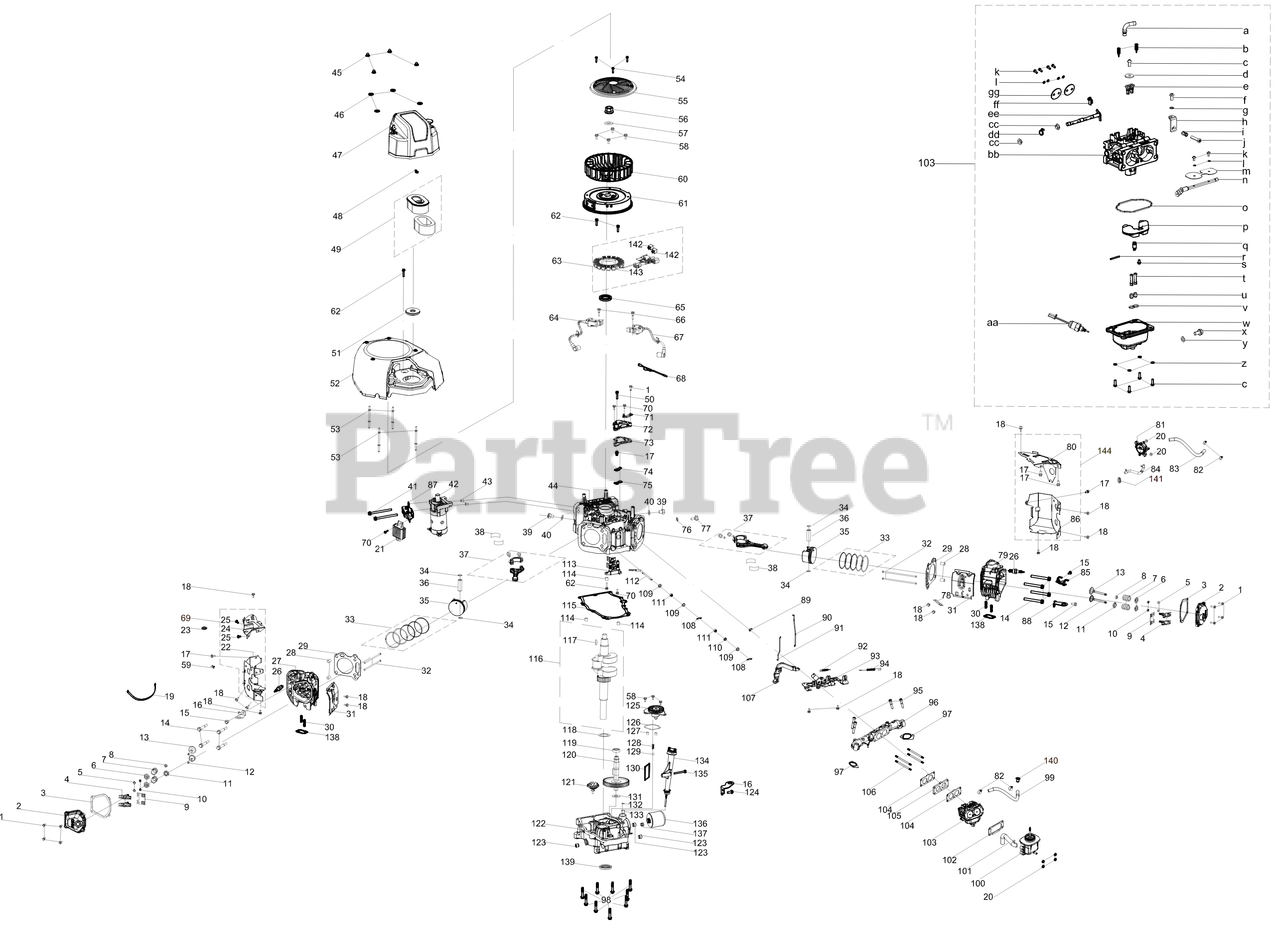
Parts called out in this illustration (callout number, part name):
1	BOLT M6 x 22
2	VALVE COVER
3	VALVE COVER GASKET
4	ROCKER ARM ASSEMBLY
5	EXHAUST VALVE ADJUSTER
6	VALVE SPRING SEAT
7	VALVE SPRING
8	INTAKE VALVE SEAL
9	PUSH ROD GUIDE
10	VALVE CAP
11	VALVE SPRING RETAINER
12	EXHAUST VALVE
13	INTAKE VALVE
14	HEX HEAD BOLT - M10X1.25X87
15	HEX HEAD BOLT M8X16
16	LIFT HOOK BRACKET - LH
17	BOLT M6-1 x 10 GR8.8
18	BOLT M6-1 x 12 GR8.8
19	CABLE TIE - 3 x 150
20	HEX NUT
21	REGULATOR
22	CYLINDER HEAD BAFFLE
23	HEAT SHIELD GROMMET
24	FLYWHEEL SHROUD - LH
25	HEX HEAD SCREW M6X10
26	SPARK PLUG
27	CYLINDER HEAD - LH
28	DOWEL PIN
29	CYLINDER HEAD GASKET
30	STUD M8 x 36
31	SHROUD
32	PUSH ROD
33	PISTON RIN SET
34	PISTON PIN SNAP RING
35	PISTON ASSEMBLY
36	PISTON PIN
37	CONNECTING ROD
38	CONNETING ROS BEARING
39	HEX HEAD BOLT M14-1.5X1.5
40	FLAT WASHER 14X1.5X22
41	HEX HEAD BOLT M8X110
42	ELECTRIC STARTER
43	DOWEL PIN
44	CRANKCASE
45	ACORN NUT
46	WASHER
47	AIR FILTER COVER ASSEMBLY
48	WING NUT
49	AIR FILTER ELEMENT
49	Genuine Factory Parts AIR FILTER
50	BOLT-M6-1 x 28 GR8.8
52	BLOWER HOUSING
53	STUD - M6-1.0X69.8X117
54	BOLT 5.5 x 25
55	DEBRIS SHIELD
56	NUT M20 x 1.5
57	WASHER 20.5 x 5 x 40
58	BOLT M6-1 x 18 GR8.8
59	PLASTIC SUPPORT CLAMP
60	COOLING FAN
61	FLYWHEEL
62	BOLT M6-1 x 25 GR8.8
63	CHARGING COIL
64	IGNITION MODULE (LH)
65	OIL SEAL 38 x 58 x 8
66	BOLT-M6-1 x 30 GR8.8
67	IGNITION MODULE (RH)
68	WIRE HARNESS
69	SHROUD ASSEMBLY (LH)
70	BOLT M6 x 16
71	FLYWHEEL GUARD BRACKET
72	BEATHER COVER
73	BREATHER COVER GASKET
74	BREATHER REED BRACKET
75	BREATHER REED ASSEMBLY
76	WASHER 20.5X1.5X18
77	HEX HEAD BOLT M10X1X10
79	CYLINDER HEAD - RH
80	SHROUD (RH)
81	FUEL PUMP
82	HOSE CLAMP
83	FUEL HOSE
84	FUEL LINE
85	MOUNTING BRACKET
86	CYLINDER HEAD BAFFLE
87	STARTER RELAY SUPPORT
88	REAR LIFT BRACKET
89	CHOKE LINKAGE LOCK CLAMP
90	THROTTLE LINKAGE
91	CHOKE LEVER
92	GOVERNOR SPRING
93	GOVERNOR GEAR BRACKET ASSEMBLY
94	GOVERNOR SPRING
95	SCREW - M8X50
96	INTAKE MANIFOLD
97	INTAKE MANIFOLD GASKET 9Q78
98	HEX HEAD FLANGE BOLT M8X48
99	FUEL LINE 6.3 x 12.5 x 470
100	INTAKE MANIFOLD
101	BREATHER HOSE
102	AIR FILTER HOUSING GASKET
103	CARBURETOR
104	CARBURETOR GASKET
105	INSULATOR
106	STUD M6-1 x 105
107	GOVERNOR LEVER
108	GOVERNOR SHAFT CLIP
109	FLAT WASHER 8.5X15.8X2
110	GOVERNOR SEAL
111	NEEDLE BEARING 8X12X10
112	GOVERNOR ARM ROD
113	ROACKER ARM
114	PIN 8X12
115	CRANKCASE GASKET
116	CRANKSHAFT ASSEMBLY
117	FLYWHEEL KEY
118	WASHER - 38.5X1.0X54
119	CAMSHAFT BEARING
120	CAMSHAFT ASSEMBLY
121	GOVERNOR GEAR
122	CRANKCASE COVER
123	ENGINE PLUG 3/8 NPT
124	HEX HEAD SCREW M8X16
125	OIL PUMP ASSEMBLY
126	OIL PUMP GASKET
127	DOWEL PIN
128	OIL PUMP SPRING
129	OIL PUMP STEEL BALL
130	OIL PUMP SCREEN
131	THRUST WASHER 17.4X25.9X1.0
132	O-RING 13.2X2.65
133	CRANKCASE OIL PASSAGE PIN
134	DIPSTICK ASSEMBLY
135	SCREW M6-1:50:CL5.
136	ENGINE OIL FILTER
136	Cub Cadet OIL FILTER
136	Genuine Factory Parts OIL FILTER
137	SCREW JOINT OIL FILTER ADAPTER
138	EXHAUST GASKET
139	OIL SEAL 38 x 58 x 8
141	GROMMET
143	CHARGING COIL
144	SHROUD ASSEMBLY (RH)
